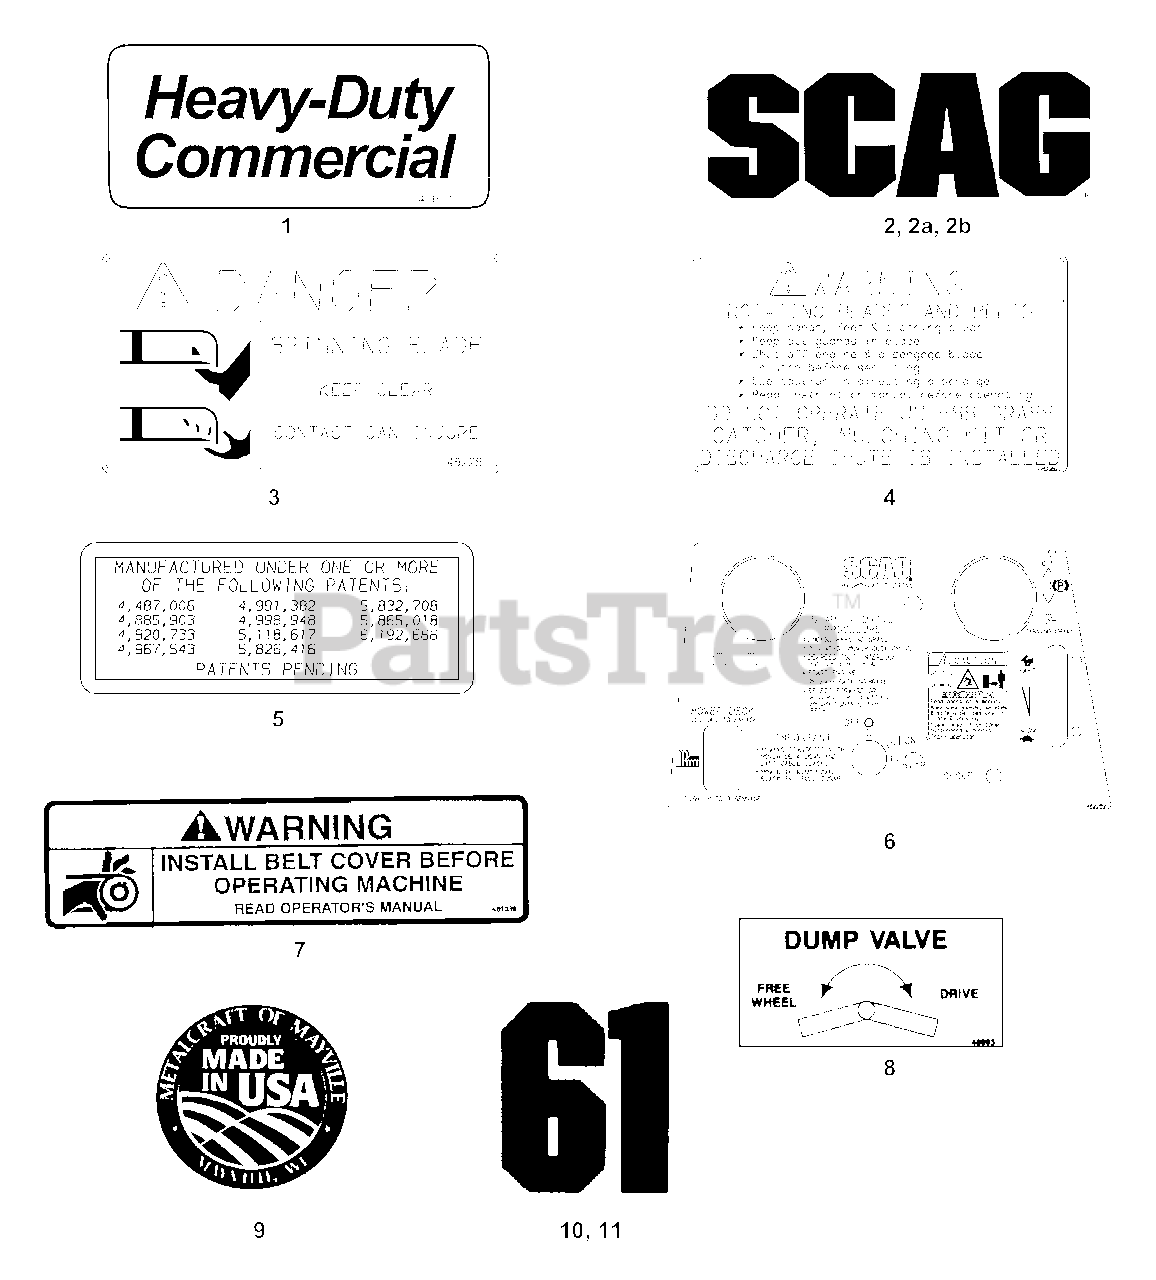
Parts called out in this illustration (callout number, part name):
1	Decal, Heavy Duty Commercial
2	Decal, Scag Logo (Cutter Deck)
2A	Decal, Scag Logo (Battery Box Front)
2B	Decal, Scag Logo Seat Back
3	Decal, Danger-Spinning Blades
4	Decal, Warning-Rotating Blades
5	Decal, Patent
6	Decal, Instrument Panel
7	Decal, Warning-Belt Cover
8	Decal, Dump Valve
9	Decal, Metalcraft-Made In USA
10	Decal, 61
11	Decal, 72
